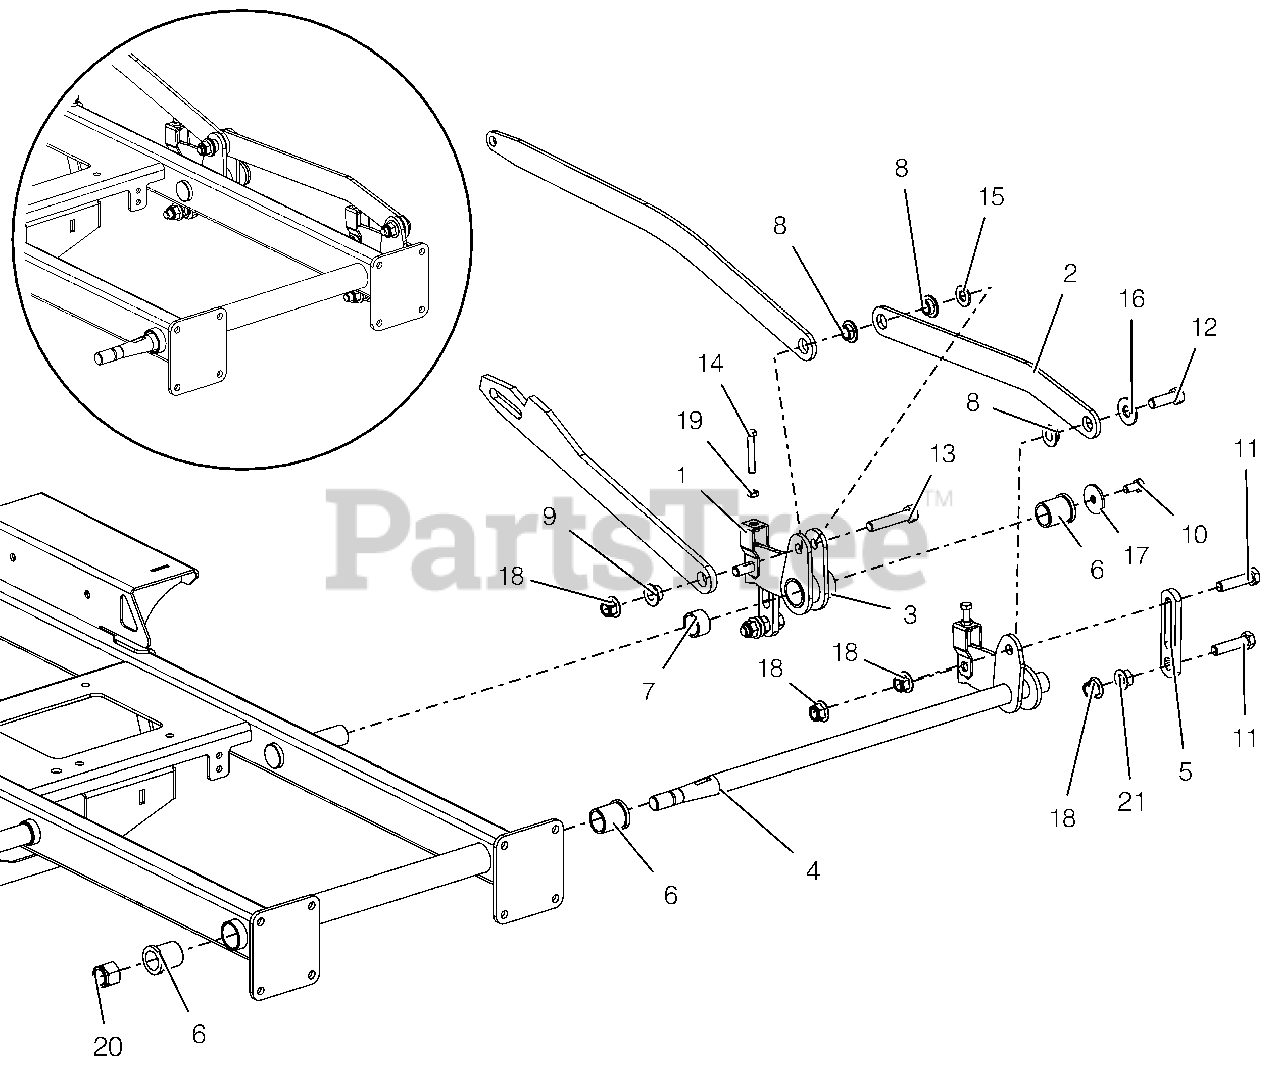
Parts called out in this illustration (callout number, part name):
1	BRKT, DECK LEVELING
2	PLATE, DECK ARM
3	WLDMT, REAR DECK ARM
4	WLDMT, FRONT LH DECK LIFT ARM
5	LINK-DECK LIFT - SHORT
6	BSHG-FLG 1.00X1.25X1.50X1.50
7	BUSH, SLV 1.00 X 1.25 X .75
8	BSHG, FLG .515X.750X.360X1.12
9	BSHG, FLG .515X.750X.480X1.12
10	@BLT-HEX .38-16X.75 GR5 YWZC
11	@BLT-HEX .50-13X2.00 GR5 YWZC
12	@BLT-HEX .50-13X1.50 GR5 YWZC
13	@BLT-HEX .50-13X2.50 GR5 YWZC
14	BLT-HEX .312-18X2.00 FTH GR5YZ
15	@WSHR-FL-STL.531X1.06X.095YWZC
16	@WSHR-FL-STL.563X1.38X.109YWZC
17	WSHR-FL-STL .380X1.50X.125YWZC
18	@NUT-LK-NYL-FLG .50-13 YWZC
19	NUT- JAM .312-18 YWZC
20	@NUT-LK-NYL .75-10 YWZC
21	NUT-SPNLK-FLG .50-13 YWZC
